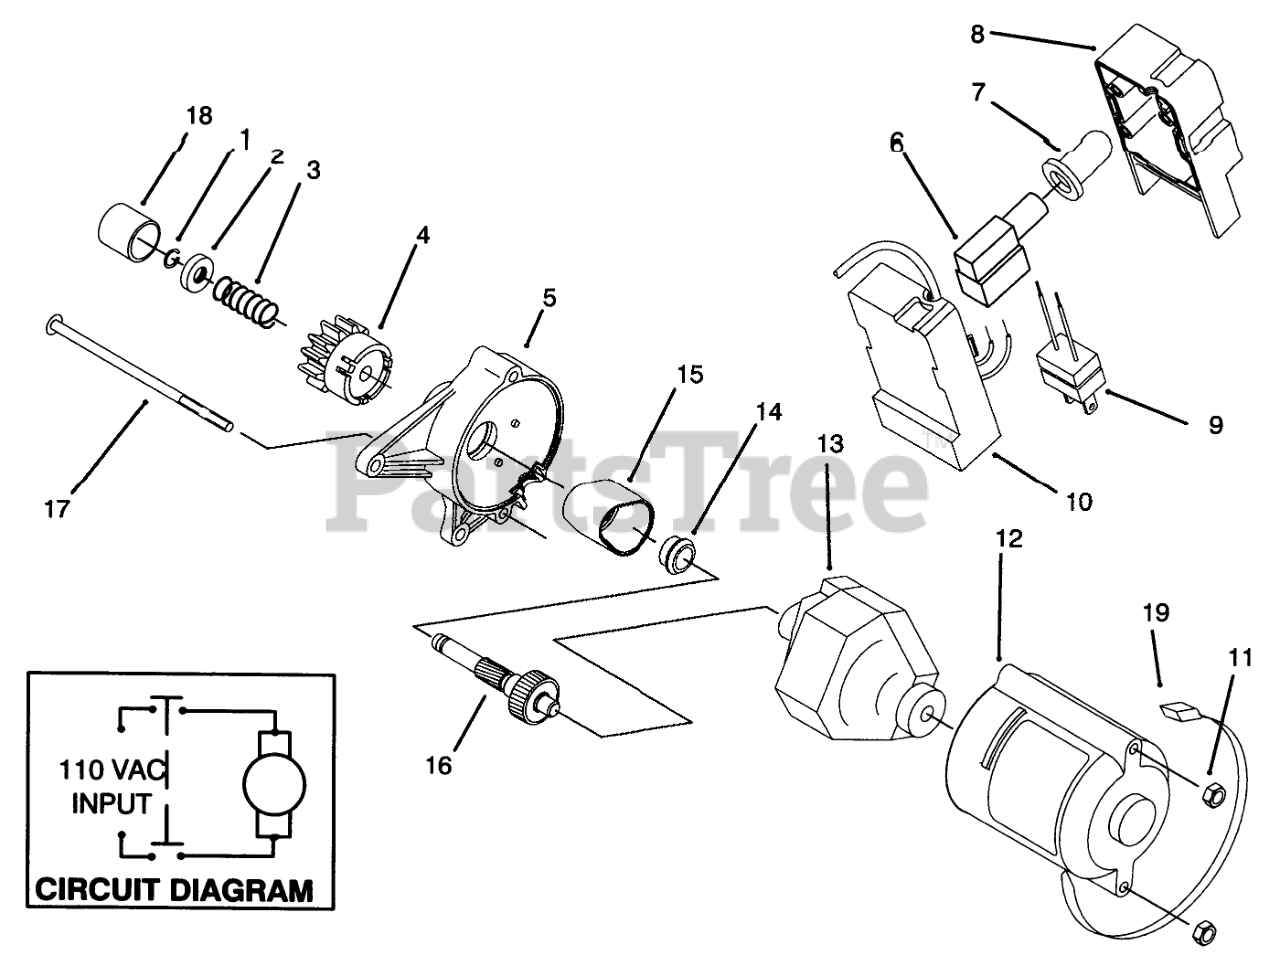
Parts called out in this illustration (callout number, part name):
1	RING-LOCK
2	PINION STOP
3	SPRING
4	PINION ASM
5	Housing-Starter
6	SWITCH-STARTER
7	BOOT-SWITCH
8	Cap-Switch Housing
9	Plug
10	OBS BASE X
11	NUT-LOCK, NI
12	HOUSING COVER
13	STARTER MOTOR ASM
14	BUSHING
15	COVER-GEAR
16	Asm-shaft & Gear
18	CAP-PINION
19	TIE-CABLE
